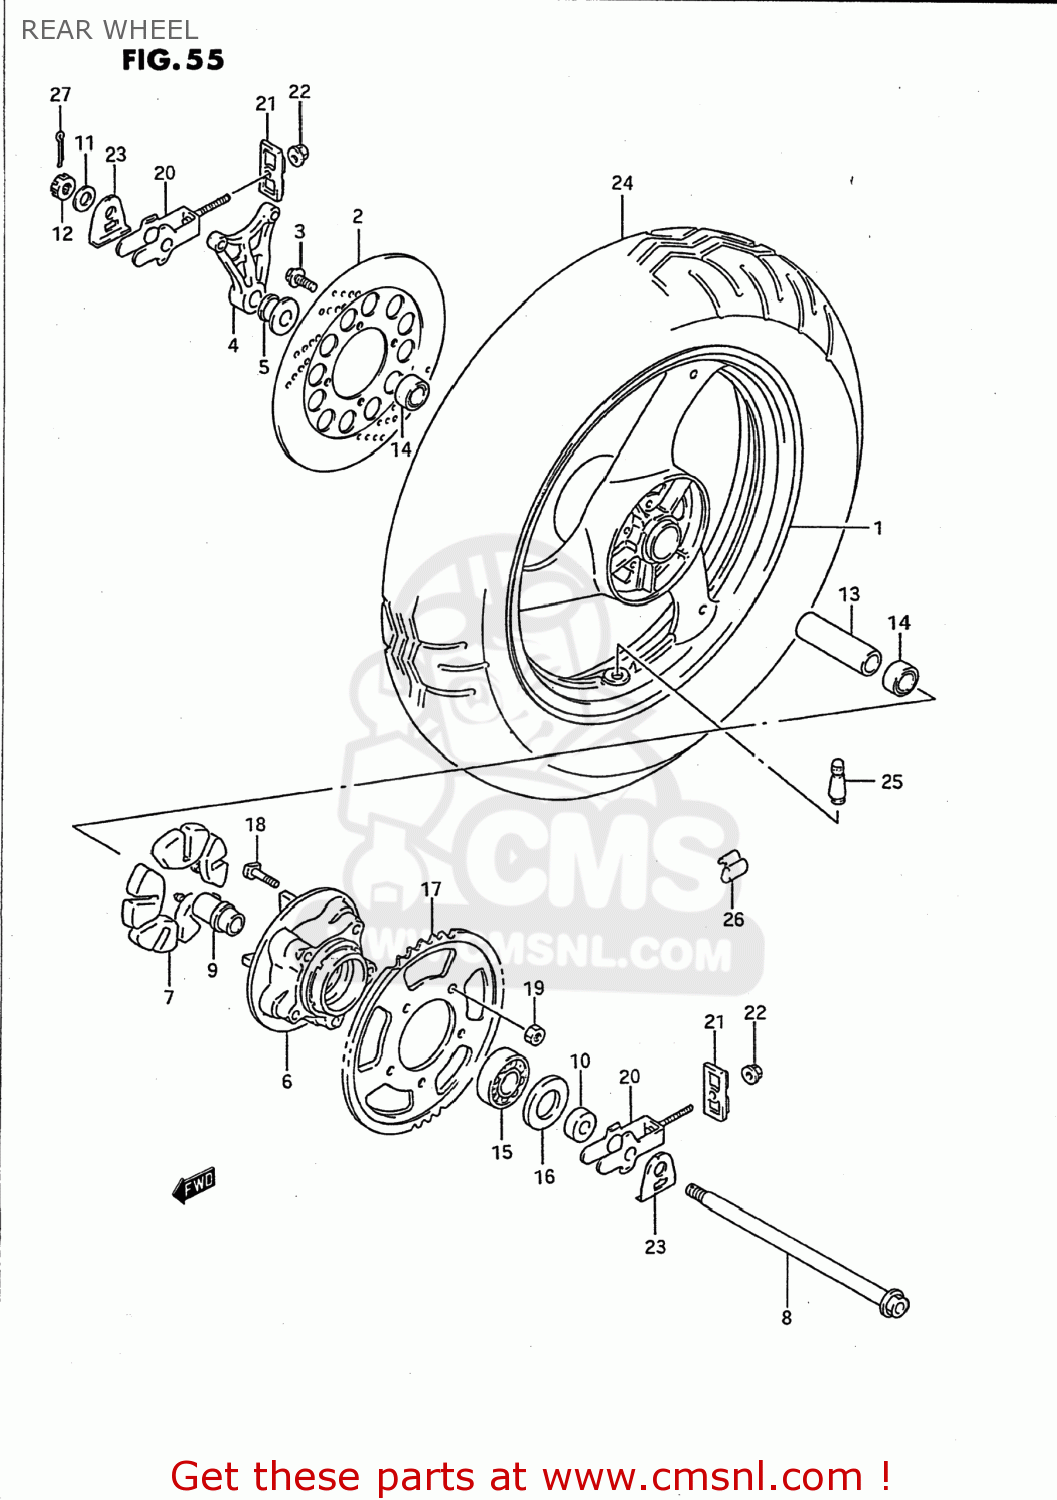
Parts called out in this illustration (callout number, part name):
1	WHEEL,REAR (MT3.50X17)
2	DISC,RR BRAKE
3	BOLT
4	BRACKET,RR,CALIPER
5	SPACER,RR AXLE,R
6	DRUM,RR SPROCKET MOUNTING
7	ABSORBER,RR HUB SHOCK
8	AXLE,REAR
9	RETAINER,RR SPROCKET DRUM
10	SPACER,RR AXLE,L
11	WASHER (17X30X3.2)
12	NUT
13	SPACER(17.5X25X88)
14	BEARING
15	BEARING(25X62X17)
16	SEAL,OIL(35X62X8)
17	SPROCKET,RR(NT:47-530)
18	BOLT
19	NUT
20	ADJUSTER,CHAIN
21	PLATE,CHAIN ADJUSTER GUIDE
22	NUT
23	WASHER,CHAIN ADJUSTER
24	TIRE
25	VALVE ASSEMBLY,WHEEL,TR412
26	BALANCER,WHEEL
27	PIN,COTTER
